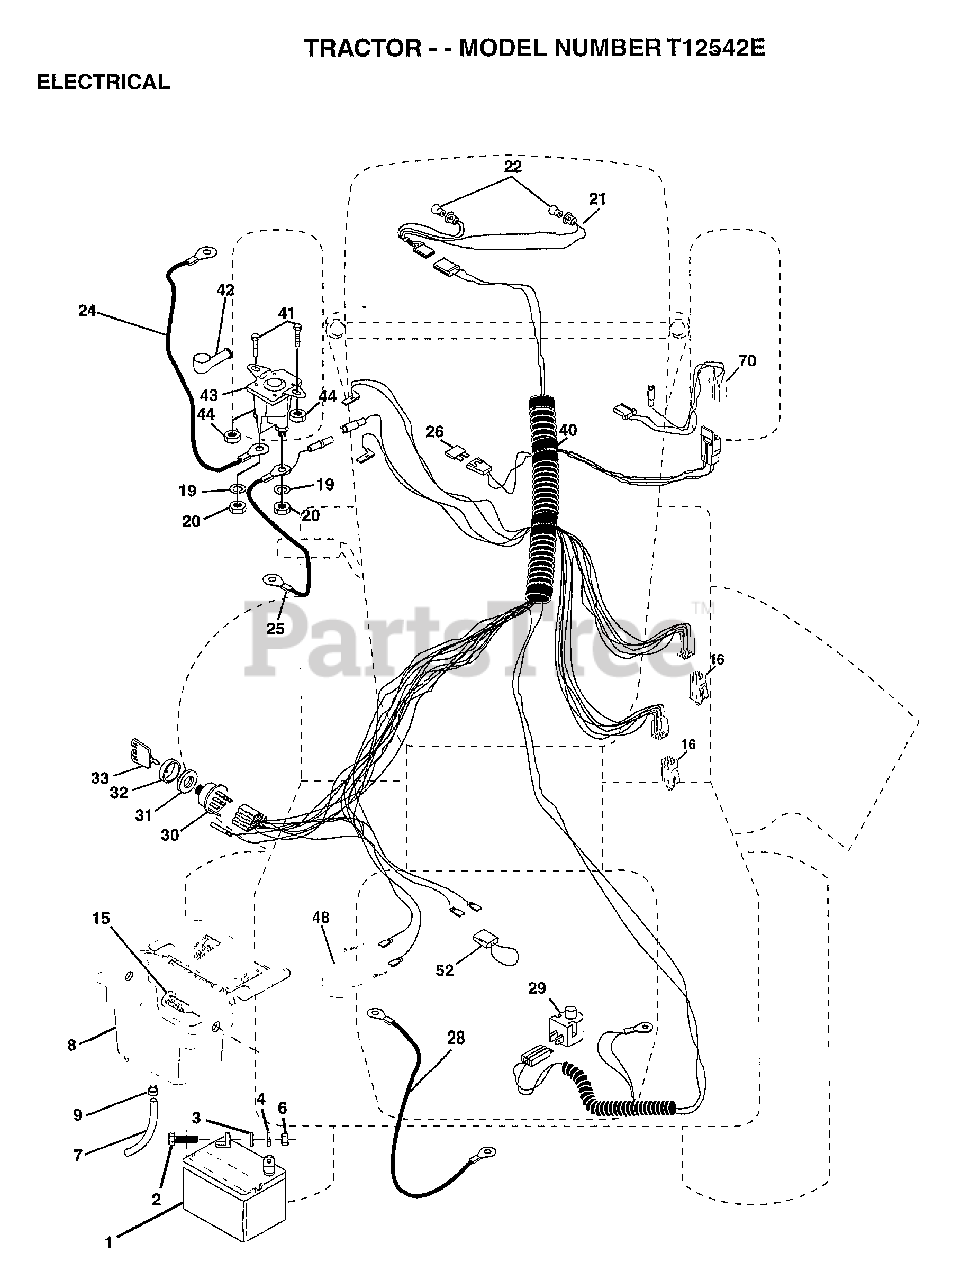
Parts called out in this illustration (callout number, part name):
2	BOLT LT
3	WASHER
4	LOCKWASHER
7	TUBE T
8	"CASE,BATTERY.MECH"
9	HOSE CLAMP T
15	FASTNER.SNAP-IN
16	SWITCH INTERLOCK
20	NUT
21	"HARNESS,LIGHT SOC"
22	HEADLAMP BULB
24	"CABLE T, BATTERY"
25	CABLE.BTRY.6GA.RD
26	FUSE HYT
28	CABLE T
29	SWITCH SEAT
30	SWITCH IGN 4POS
31	NUT IGNITION
32	COVER KEY SWITCH
33	KEY
40	HARNESS-IGNITION
41	BOLT HXHD FIN
44	NUT HXKEP 1/4X20
48	ADAPTER AMMETER
52	PROTECTION LOOP
70	HARNESS ENG DUAL
